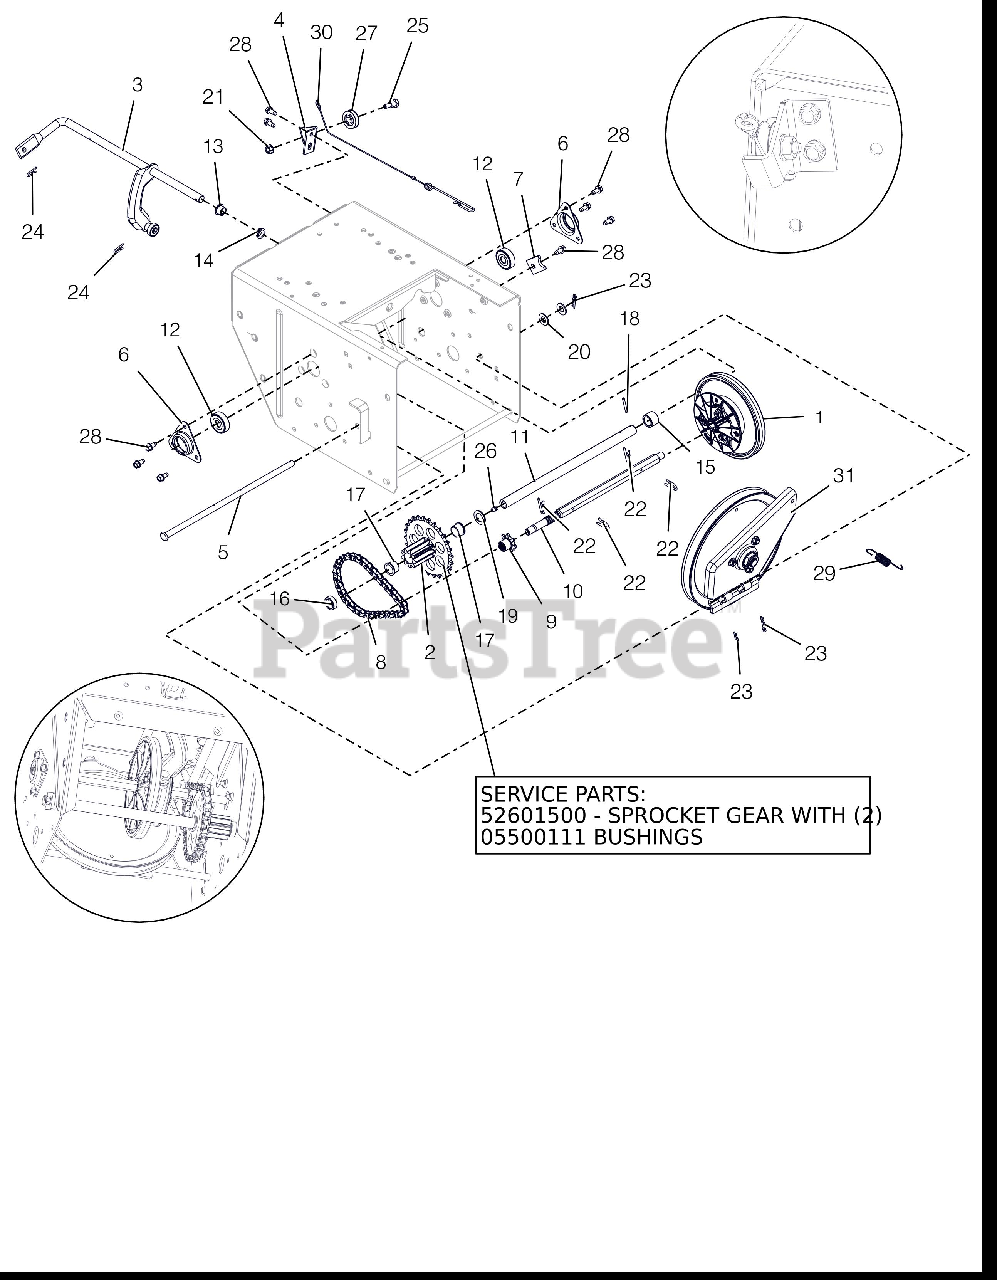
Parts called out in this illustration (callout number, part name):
1	DISC, FRICTION DRIVE-ASSEMBLY
2	PINION & SPROCKET
2	PINION & SPROCKET W/BUSHINGS
2	BSHG-FLG .625X.750X.500X.875
3	ARM, SHIFT-PRO (ASSEMBLY)
4	BRACKET, CABLE PULLEY
5	PIN, PIVOT
6	FLANGE, BEARING
7	TAB, ANTI ROTATION
8	CHAIN - #41, 32 PITCHES
9	SPROCKET, PINION 7T W/SPLINE
10	SHAFT, HEX - HEAT TREATED
11	SHAFT, PINION - HARDENED
12	BRG-BALL .437X1.375X.437
13	BUSHING, POLYLINER-.50 SPLIT
14	BUSHING, POLYLINER-.50 SNAPIN
15	SPACER, .635X.880X.611
16	BSHG-SLV, .635X.880X.305
17	BSHG-FLG .625X.750X.500X.875
18	PIN-ROLL .125X1.00
19	WSHR-FL-STL .630X1.005X.062 YZ
20	@WSHR-FL-STL.406X.812X.065 YWZ
21	@NUT-LK-TOP-FLG .25-20 YWZC
22	PIN, SPRING CLIP
23	PIN-HAIR, ENDRIES #25 YWZC
24	CLIP, SPRING
25	BOLT, SHLDR-.375X.375X.25-20
26	ZERK,FITTING .25X.125 DRIVE IN
27	PULLEY, CABLE
28	SCR-TAP .25-20X.50 HWH TR YWZ
29	SG-TENS .048X.50X2.8
30	CABLE, LOWER TRACTION,SS & PRO
31	PLATE, SWING ASSEMBLY-DEEP
